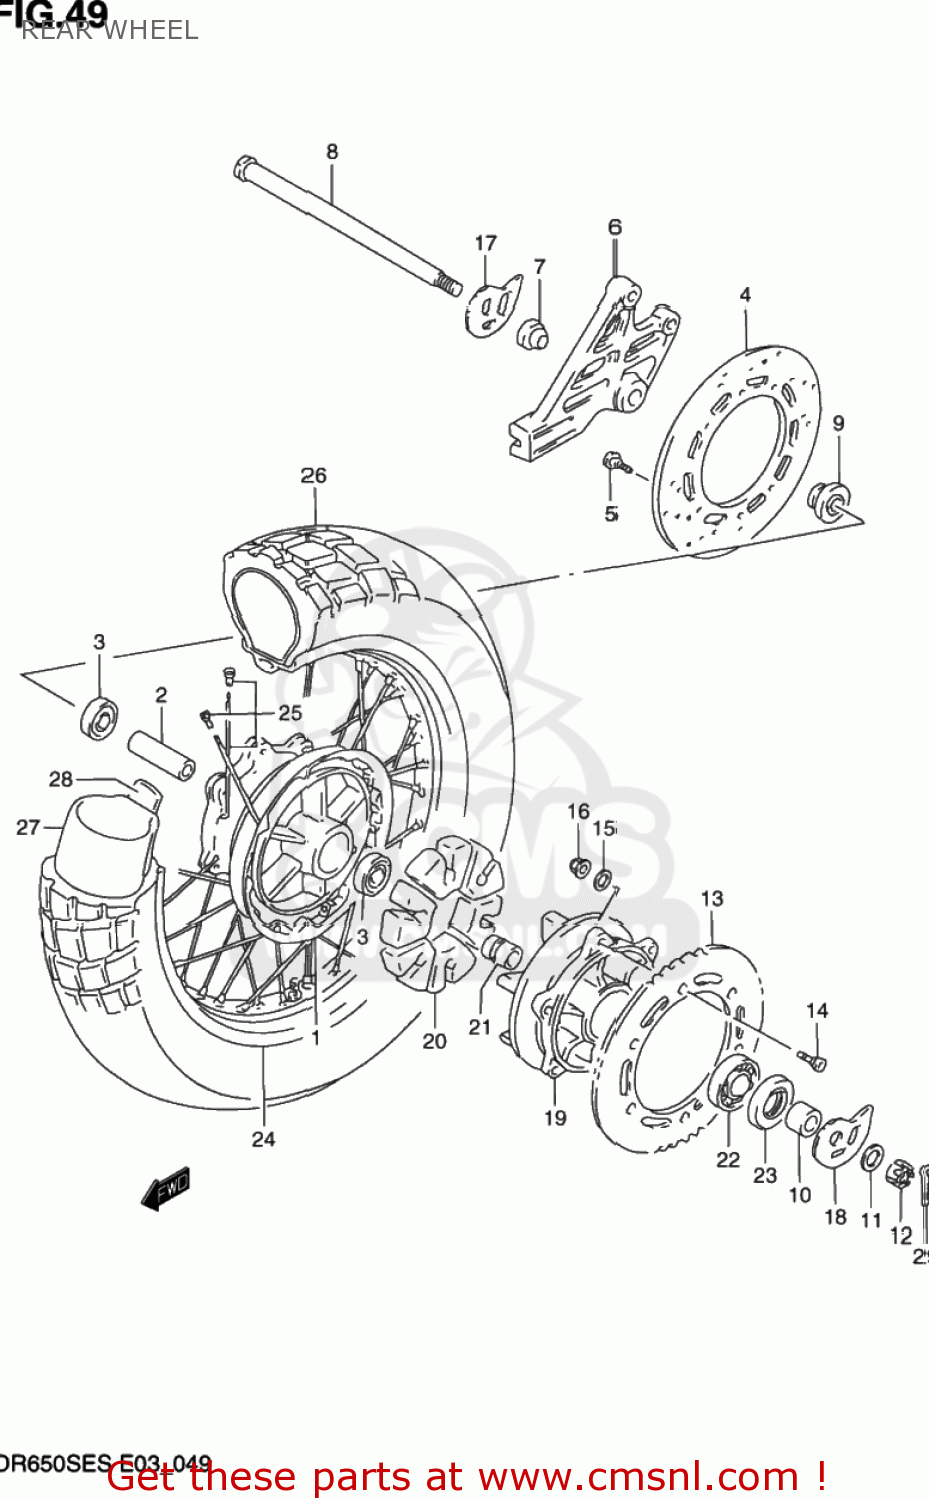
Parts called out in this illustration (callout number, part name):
1	HUB COMP,REAR WHEEL
2	SPACER(17.5X25X78)
3	BEARING
4	DISC,RR BRAKE
5	BOLT,BRAKE DISC
6	BRACKET,RR CALIPER
7	SPACER (17X21X10)
8	AXLE,REAR
9	SPACER,RR AXLE,L
10	SPACER(17X33X22.4)
11	WASHER (17X30X3.2)
12	NUT
13	SPROCKET,RR(NT:42)
14	BOLT(8X30.5)
15	WASHER
16	NUT
17	ADJUSTER,CHAIN,R
18	ADJUSTER,CHAIN,L
19	DRUM,REAR SPROCKET
20	ABSORBER,RR HUB SHOCK
21	RETAINER,RR SPROCKET DRUM
22	BEARING(25X62X17)
23	SEAL,OIL(33X62X7)
24	RIM,RR WHEEL(17XMT2.50)
25	SPOKE SET,RR
26	TIRE,REAR 120/90-17 64
27	TUBE ASSY,WHEEL INNER
28	PROTECTOR,WHL INR TUBE
29	PIN,COTTER
